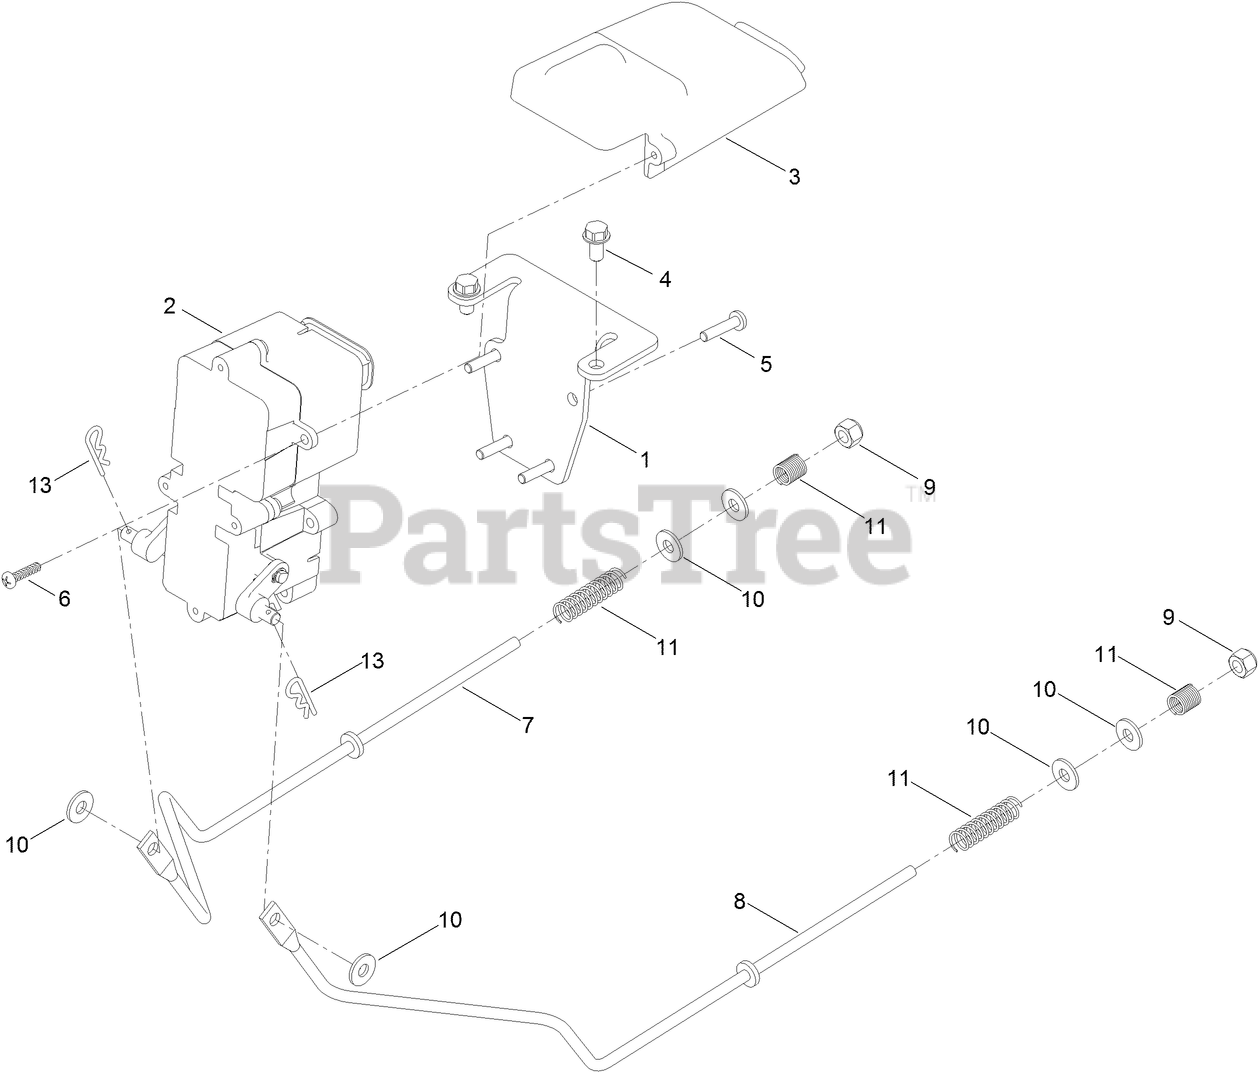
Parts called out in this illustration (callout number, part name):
1	BRACKET-MOUNT, BRAKE
2	BRAKE BOX ASM
3	COVER-CONNECTOR
4	SCREW-HWH
5	SCREW-PPH
6	SCREW-PPH
7	ROD-BRAKE, WIDE (RH)
8	ROD-BRAKE, WIDE (LH)
9	NUT-LOCK, NI
10	WASHER
11	SPRING-COMPRESSION
